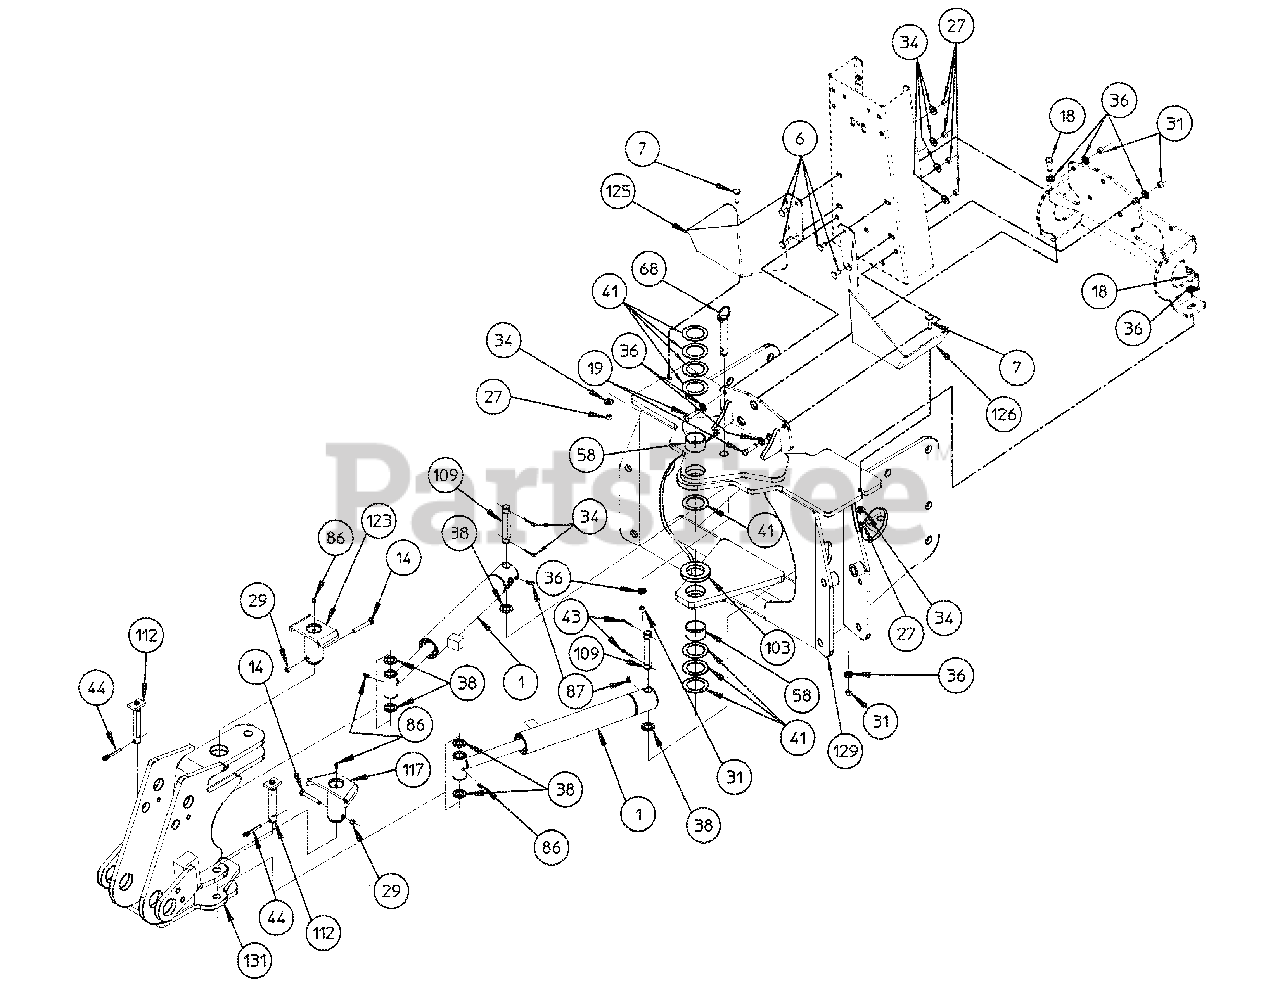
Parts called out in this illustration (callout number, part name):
1	Hydraulic Cylinder - Swing
2	Hydraulic Cylinder - Bucket
3	Hydraulic Cylinder - Stabilizer
4	Hydraulic Cylinder - Boom
5	Hydraulic Cylinder - Dipper
6	Bolt, Carriage 5/16 NC x 3/4"
7	Bolt, Carriage 5/16 NC x 1-1/4"
8	Bolt, 1/4 NC x 3/4"
9	Bolt, 5/16 NC x 3/4"
10	Bolt, 5/16 NC x 3/4" Thread Forming
11	Bolt, 5/16 NF x 3/4"
12	Bolt, 5/16 NF x 7/8"
13	Bolt, 5/16 NF x 1" Gr. 5
14	Bolt, 5/16 NF x 2-1/4" Gr. 5
15	Bolt, 5/16 NF x 2-1/2" Gr.5
16	Bolt, 5/16 NF x 4" Gr. 8
17	Bolt, 3/8 NF x 3/4"
18	Bolt, 3/8 NF x 1"
19	Bolt, 3/8 NF x 1-1/4"
20	Bolt, 3/8 NF x 1-3/4"
21	Bolt, 3/8 NF x 2-1/4"
22	Bolt, 3/8 NF x 2-3/4"
23	Bolt, 3/8 NC x 5-1/2" Long Gr.5
24	Bolt, 1/2 NF x 7/8"
25	Nut, 1/4 NC
26	Nut, 5/16NC
27	Locknut, 5/16 NC
28	Nut, 5/16 NF
29	Locknut, 5/16 NF
30	Lock Nut, 3/8NC
31	Locknut, 3/8 NF
32	Lockwasher, 1/4
33	Lockwasher, 5/16
34	Flat Washer. 5/16 STD
35	Washer, 5/16 SAE
36	Flat Washer, 3/8 SAE
37	Flat Washer, 1/2" Hardened
38	Machine Bushing, 1-1/4 OD x 3/4 ID x 14Ga.
39	Machine Bushing 1-1/2" OD x 1" ID x 18Ga.
40	Machine Bushing 1-7/8" OD x 1-1/4" ID x 18Ga.
41	Machine Bushing, 2-1/2 OD x 1-3/4ID x 18Ga
42	Cotter Pin, 3/32" Dia x 3/4"
43	Cotter Pin, 3/16 x 1-1/4"
44	Cotter Pin, 1/4 x 1-1/2"
45	Hair Pin Cotter, 3/64" Dia x 11/16"
47	Adapter Union, 9/16-18M x 3/8NPTF
48	Hydraulic Tee
49	Adapter Union, 3/4-16M x 3/8NPTF x Straight
50	Adapter Union, 3/8NPTM x 3/8NPTF x 90 degree
51	Adapter Union, 9/16-18M x 3/8NPTF x 90 degree
52	Adapter Union, 7/8-14M x 3/8 NPTF x 90 degree
53	Adapter Union, 3/4-16M x 3/8NPTF x 90 degree
54	Coupler Body 3/4-16F Thread
55	Coupler Nose 3/4-16F Thread
56	Garlock Bearing, 028DXR020
57	Bronze Bearing
58	Garlock Bearing, 028DXR016
59	Stabilizer Pad Weldment
60	Guide Link
61	Bucket Link
62	Street Pad
63	Clevis Pin, 3/16" Dia x 5/8"
64	Clevis Pin, 1/4" Dia x 7/8"
65	Pin Retainer
66	Pin Retainer
67	Boom Lock Pin
68	Swing Lock Pin
69	SMV Socket
70	SMV Bracket
72	Ball Joint - Shouldered
73	Ball Joint
74	Control Knob
75	Rubber Cap
76	Plastic Tie T150L
77	Plastic Tie T120 L
78	Plastic Tie T50L
80	Hose Sleeve FC425-16 X 30" Long
81	Hose Sleeve FC425-16 X 19" Long
82	Hose Sleeve FC425-16 X 48" Long
83	Hose Sleeve FC425-16 X 63" Long
84	Hose Sleeve FC425-16 X 79" Long
85	Grease Fitting
86	Grease Fitting (Two are part of #000187 Cyl.)
87	Grease Fitting (Two are part of #000187 Cyl.)
88	Hydraulic Hose, 3/8NPTM x 3/8NPTM x 20" long
89	Hydraulic Hose, 3/8NPTM x 3/8NPTM x 23" long
90	Hydraulic Hose, 3/8NPTM x 3/8NPTM x 30" long
91	Hydraulic Hose, 3/8NPTM x 3/8NPTM x 58" long
92	Hydraulic Hose, 3/8NPTM x 3/8NPTM x 76" long
93	Hydraulic Hose, 3/8NPTM x 3/8NPTM x 92" long
94	Hydraulic Hose, 3/8NPTM x 3/8NPTM x 110" long
95	Hyd. Hose, 3/8ID 3/8NPTF M x 3/4-16 Str O x 49"
96	Hyd. Hose, 3/8ID 3/8NPTF M x 3/4-16 Str O x 34"
97	Control Valve
98	Adapter Union, 7/16-20M x 3/8NPTF
99	Rear Shroud
100	Stabilizer Lever Control Rods
101	Control Rod
102	Pivot Pin, Boom Cyl. Rod 1-1/4" Dia. x 6" Long
103	Thrust Washer
104	Pivot Pin, Bucket 1"Dia. x 7-3/8" Long
105	SMV Socket Mount
106	Stabilizer Control Lever
107	Lever Bracket
108	Hose Clamp - Short
109	Pivot Pin, 3/4" Diameter x 4-1/16" Long
110	Pivot Pin, Dipperstick 1-1/4" Dia. x 7-15/16" Long
111	Pivot Pin, Stabilizer Leg
112	Pivot Pin Weldment
113	Pivot Pin, Stabilizer Pad 3/4" Dia. x 4-15/16" Long
114	Pivot Pin, Stabilizer Cyl. Rod
115	Pivot Pin, Bucket Cyl. Base 1" Dia. x 5-7/8" Long
116	Pivot Pin, Boom Cyl. Base 1-1/4" Dia. x 7-1/4" Long
117	Lower Pivot Pin Weldment
118	Seat Plate Weldment
119	RH Pivot Weldment
120	LH Pivot Weldment
122	Stabilizer Leg Weldment
123	Upper Pivot Pin Weldment
124	Pivot Pin Weldment, Boom 1-3/4" Dia. X 2-3/4" Lg
125	RH Toe Shield
126	LH Toe Shield
127	Hose Clamp - Long
128	Grab Bar Weldment
129	Mainframe Weldment
130	Valve Mount Weldment
131	Swing Frame Weldment
132	Front Shroud Weldment with Decals
133	Dipperstick Weldment
134	Boom Weldment
135	Right Hand Joystick Weldment
136	Left Hand Joystick Weldment
